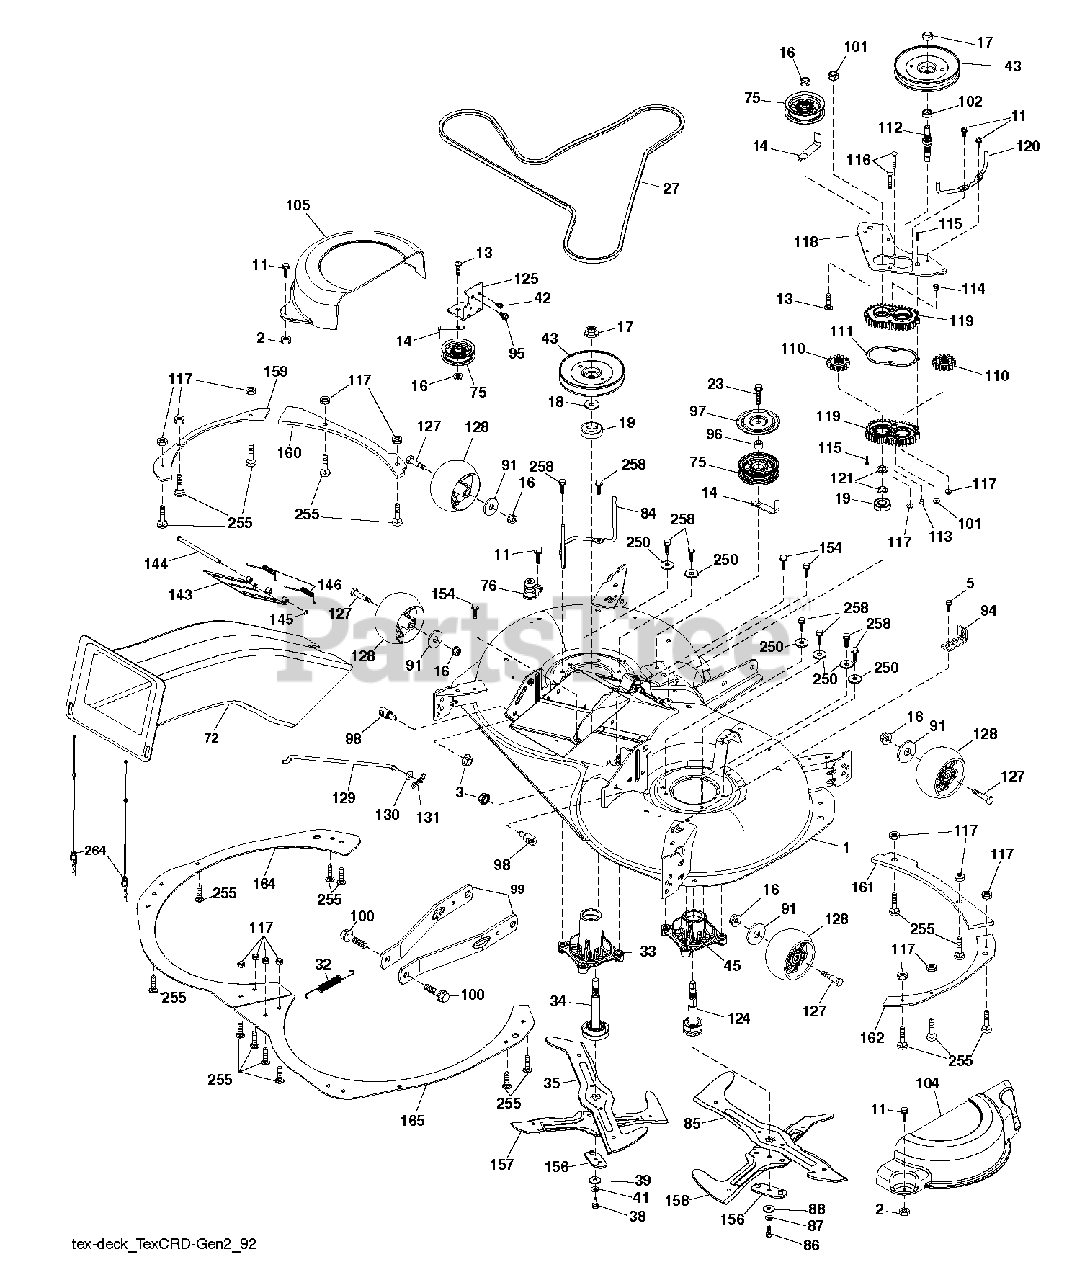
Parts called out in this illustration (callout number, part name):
1	DECK SVC 107HP.EZMUL.498
2	PALNUT 1/4
3	NUT LOCK HEX FLANGE 5/16-18
5	BOLT.5/16HEX.WHS.HD
11	SCREW.1/4-20X5/8
13	BOLT.3/8-16X1.50
14	KEEPER, BELT IDLER
16	NUT LOCK FLG 3/8-16 UNC
17	NUT.FLANGE.LOCK.TOP
18	WASHER.SPACER.MANDREL
19	BEARING.MANDREL.TOP.EXTENDED
23	SCREW LT
27	BELT.ELECT.MOWER.DRIVE 97.8 EL
32	SPRING 107CM & 97CM ELECTRIC D
33	HOUSING.MANDREL.4PT.
34	SHAFT ASM.MNDRL.N/GREASEABLE
35	BLADE.3N1.LH.CRD
38	BOLT.BLADE.7/16-20 X 1.5 GR8
39	Flat Washer, 7/16"
41	WASHER 7/16 LOCK
42	SCREW
43	PULLEY PULLEY MANDREL 5.438 PD
45	HOUSING.MANDREL.44/46" VENT
72	CHUTE.SLOTTED.HOLES.TEX.CRD.II
75	FLAT IDLER PULLEY
76	PORT.WASHOUT
84	KEEPER KEEPER. LH MANDREL BELT
85	BLADE.3N1.RH.CRD
86	BOLT.3/8-24X1.25GR8. LHTHRD
87	SLW 3/8 STD
88	WASHER.BLADE
91	WASHER
94	BRKT.CLUTCH.CABLE
95	SCREW, 3/8-16X3/4
96	SPACER
97	PROTECTOR
98	STUD.FASTNER.W/ANTI-ROTATE
99	ARM.SUSPENSION.MOWER.R
100	BOLT.SHOULDER
101	NUT.CROWNLOCK.9/16 -18.UNC
102	SPACER BEARING
104	COVER.MANDREL.107.RH.GEN.2
105	COVER.MANDREL.107.LH.GEN.2
110	CRD.SPUR.GEAR
111	GASKET GASKET GEARCASE
112	SHAFT SHAFT. CRD GEARCASE ADAP
113	PLUG PLUG OIL
114	VENT.BREATHER.1/8 NPT
115	SCREW
116	BOLT.CARIGE.SS.1/4-20X1.75GR5
117	NUT T
118	ARM ARM. CLUTCHING 107 TEX CRD
119	GEARCASE GEARCASE SUBASM
120	KEEPER KEEPER. RH MANDREL BELT
121	WASHER WASHER
124	MANDREL SHAFT NON/GREASE
125	BRACKET BRACKET IDLER CHASSES
127	BOLT.SHOULDER.3/8-16X3-5/8.
128	WHEEL. GUAGE RALLY
129	ROD ROD. SWAY CRD GEN II
130	WASHER
131	PIN.COTTER.5/16.BOW TI
143	COVER DOOR.107 CM CRD EZ MULCH
144	PIN PIN.HINGE
145	E-RING.5/16"
146	SPRING SPRING: EZ MULCH DOOR
154	SCREW T-30 1/4-20 X
156	ADAPTER ADAPTER.CROSSBLADE.107
157	BLADE 107CM.CROSS.BLADE
158	BLADE.CROSS.RH.CRD.107
159	REINFORCE.PLATE.LH.FT.X431
160	REINFORCE.PLATE.LHS.BOLT.431
161	REINFORCE.PLATE.RH.FRT.X431
162	REINFORCE.PLAT.RH.SD.BLT.X431
164	BAFFLE.PLATE.PNT.107CRD.LT.BLK
165	BAFFLE.PNT.107.CRD.PLATE.RT.BK
255	RHSNB, 1/4-20 X 1, GR5
258	BOLT.HEX.WASHR.HED.313-18X1.19
264	RETAINER.ASM.UPPERCHU
